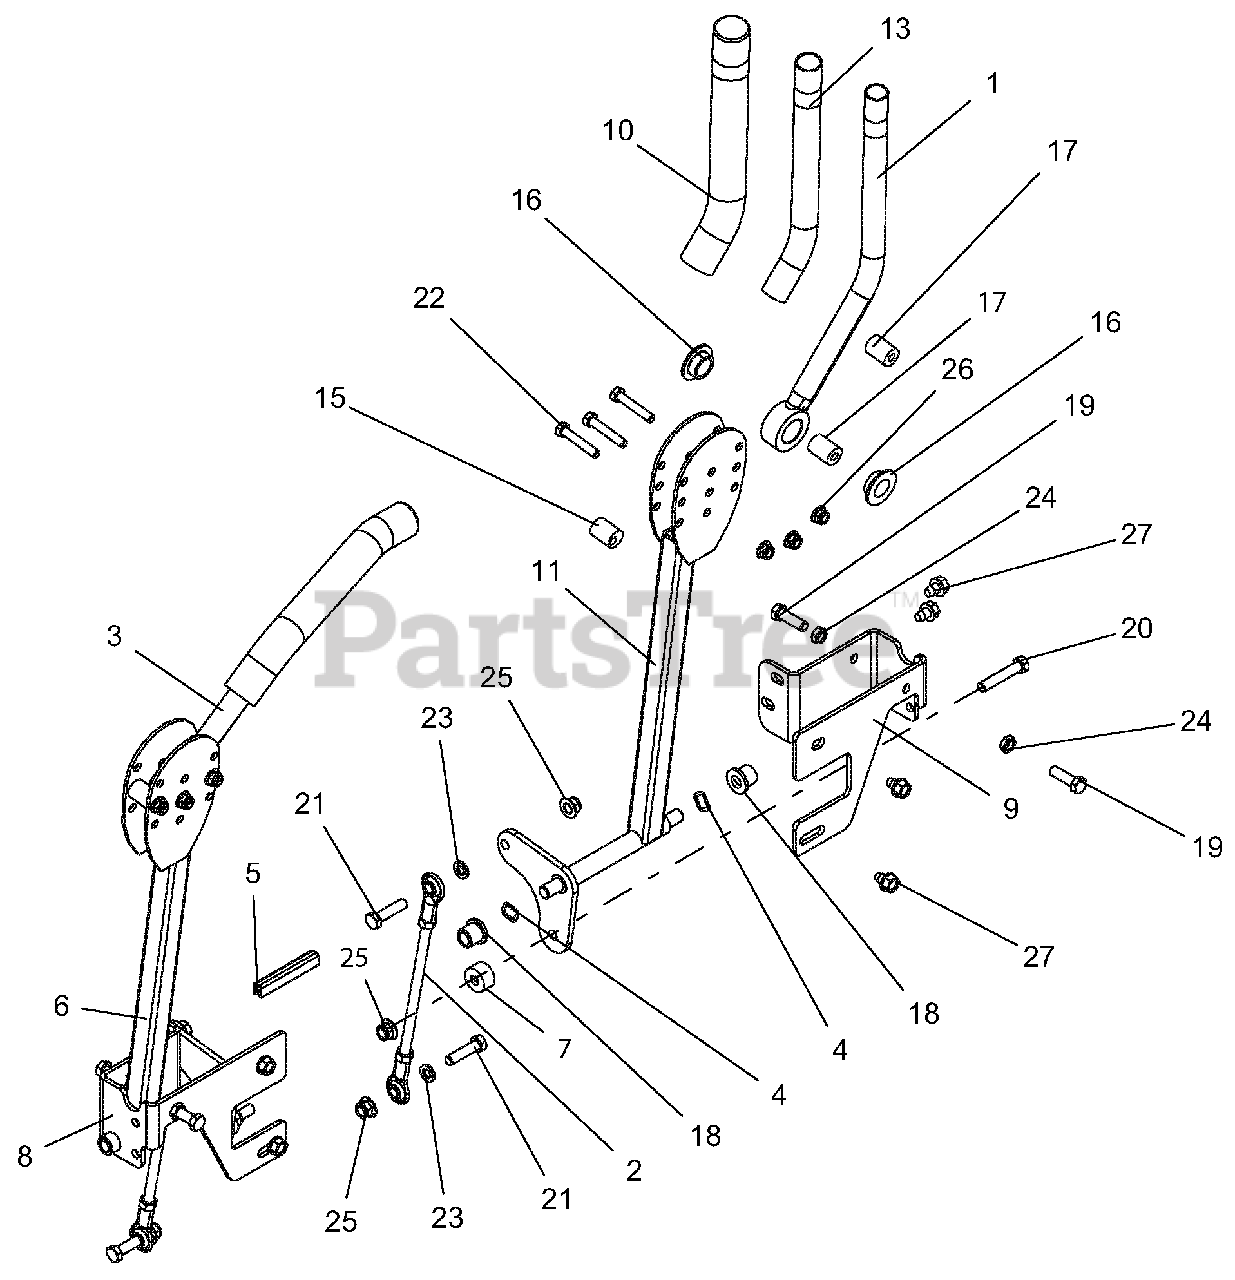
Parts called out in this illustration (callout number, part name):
1	WLDMT, LH HANDLE
2	ASM, STEERING LINKAGE
3	WLDMT, RH HANDLE
4	WAVE WASHER .531X.781X.125 FH
5	STRIP, COWL - 1.50 LG
6	WLDMT, PT/PT100 CONTROL ARM-BLACK
7	SPACER .390X1.000X.562
8	BRKT, RH STEERING STOP-RED
9	BRKT, LH STEERING STOP-RED
10	GRIP, HANDLEBAR
11	WLDMT, LH PT/PT100 CONTROL ARM
13	TUBE, .88ID X 1.00OD X 10.25
15	BSHG, ECCENTRIC .328 X .750 X .970
16	BSHG, FLANGE .762 X 1.48 X .44 NYLON
17	SPACER, .328 X .76 X 1.01
18	BHSG-FLG .500X.750X.750X.125
19	BLT-HEX .38-16X1.25 GR5 YWZC
20	BLT-HEX .38-16X2.00 FTH GR5 YWZC
21	BLT-HEX .38-16X1.50 GR5 YWZC
22	BLT-HEX .31-18X1.75 GR5 YWZC
23	WSHR-LK .38X.094 REG YWZC
24	NUT, JAM .375-16 YWZC
25	NUT-LK-NYL-FLG .38-16 YWZC
26	NUT-LK-NYL-FLG .31-18 YWZC
27	SCR-TAP .38-16X.50 HWH TR YWZ
